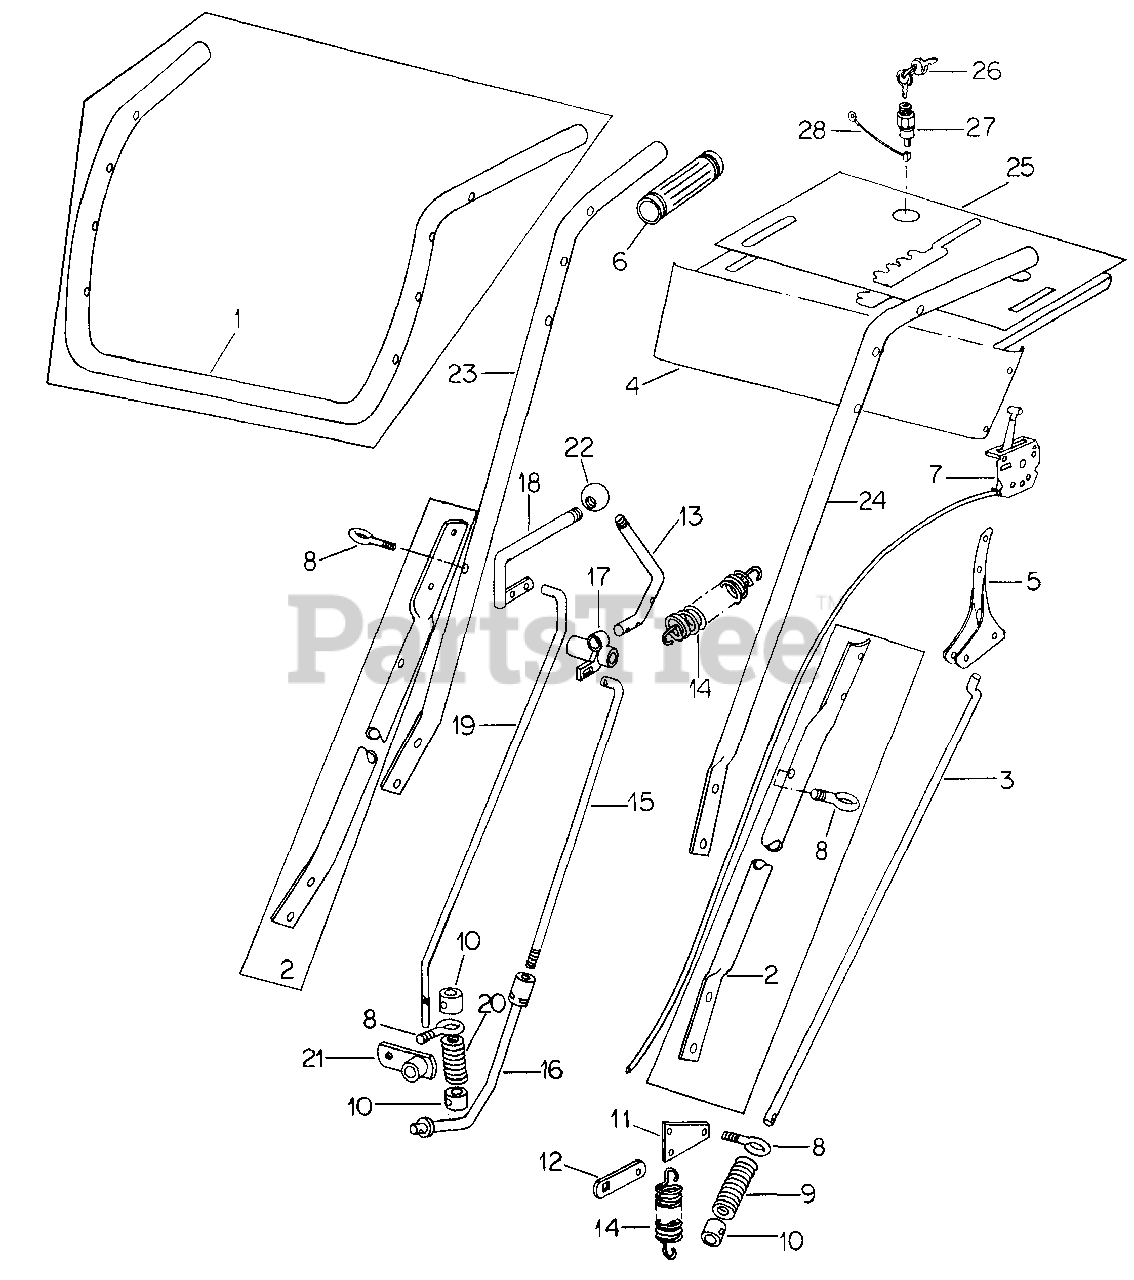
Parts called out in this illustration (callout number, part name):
1	BAR. HANDLE
2	EXTENSION, HANDLE BAR
3	ROD, CLUTCH
4	PANEL W/CAUTION PRODUCT GRAPHIC, 75746-C1, DASH
5	HANDLE, CLUTCH
6	GRIP, RUBBER HANDLE
7	CONTROL, THROTTLE
9	SPRING, CLUTCH ROD
10	BUSHING, ADJUSTING
12	BAR, CONNECTING
13	LEVER, SHIFT
14	SPRING, EXTENSION
15	ROD, CONTROL ADJUSTABLE
16	ROD ASSY, SHIFT CONTROL
17	BEARING, SPEED CONTROL PIVOT
18	HANDLE ASSY, ROTOR CONTROL
19	ROD, ROTOR CONTROL
21	ARM, CLUTCH
23	BAR, HANDLE RIGHT
24	BAR, HANDLE LEFT
25	PRODUCT GRAPHIC, DASH PANEL - CAUTION
26	KEY, SET OF TWO
27	SWITCH ASSY, KEY
28	CABLE GROUND
